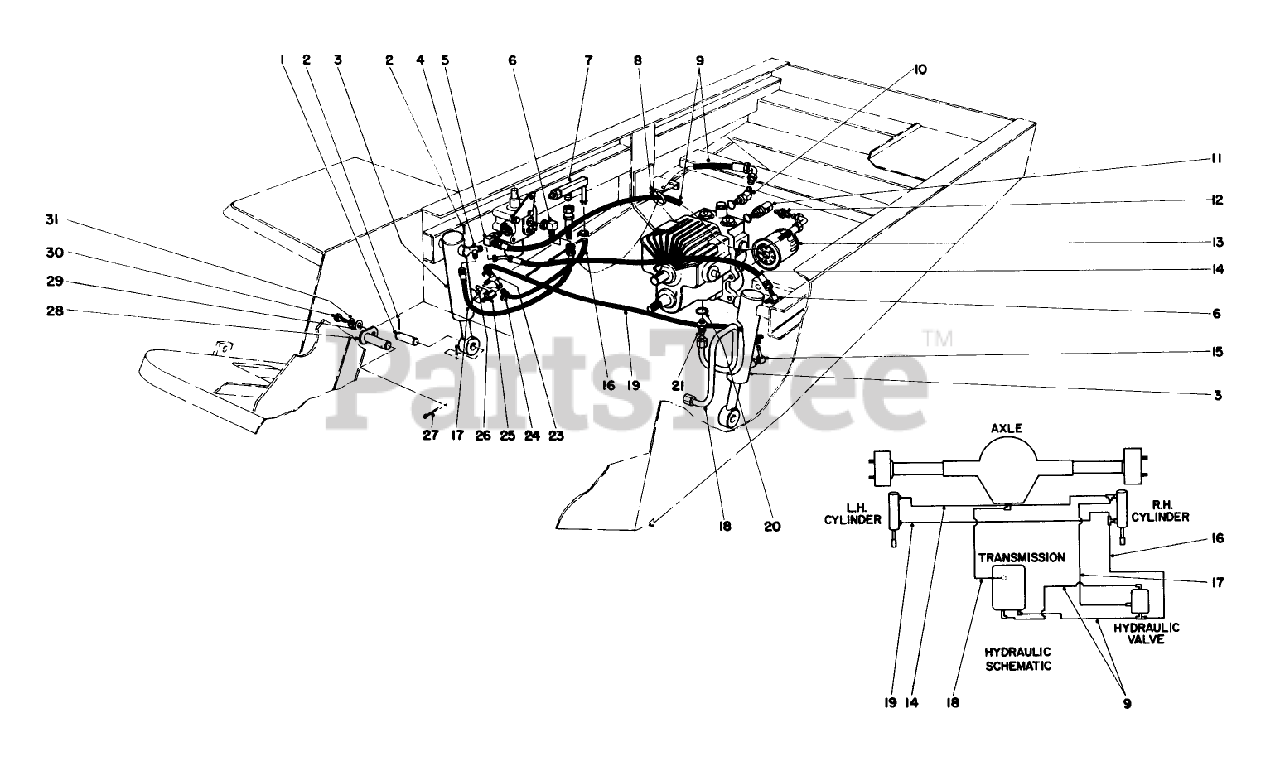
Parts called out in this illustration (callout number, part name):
1	PIN-CYLINDER
2	PIN-COTTER
3	Lift Cylinder
4	FITTING-TEE, ADJ.
5	FITTING-ELBOW, 90 DEG
6	FITTING-ELBOW, 90
7	Fitting Assembly
8	TIE-CABLE
9	TRANS-VALVE HOSE
10	FITTING-ELBOW, 45 DEG
11	SPECIAL FITTING PP
12	Adapter
13	FILTER-OIL, TRANSMISSION
14	RH CYL HOSE
15	STEM-HOSE
17	RH HOSE
18	HYORAULIC TUBE
19	HOSE-FUEL
20	O-RING
21	Fitting (Incl. Ref. #20)
23	MALE TEE FITTING
24	CLAMP-HOSE
25	CONN FITTING
26	O-RING
27	PIN-COTTER
28	Pin-Pivot
29	WASHER-FLAT
30	SCREW-HH
31	WASHER-LOCK
